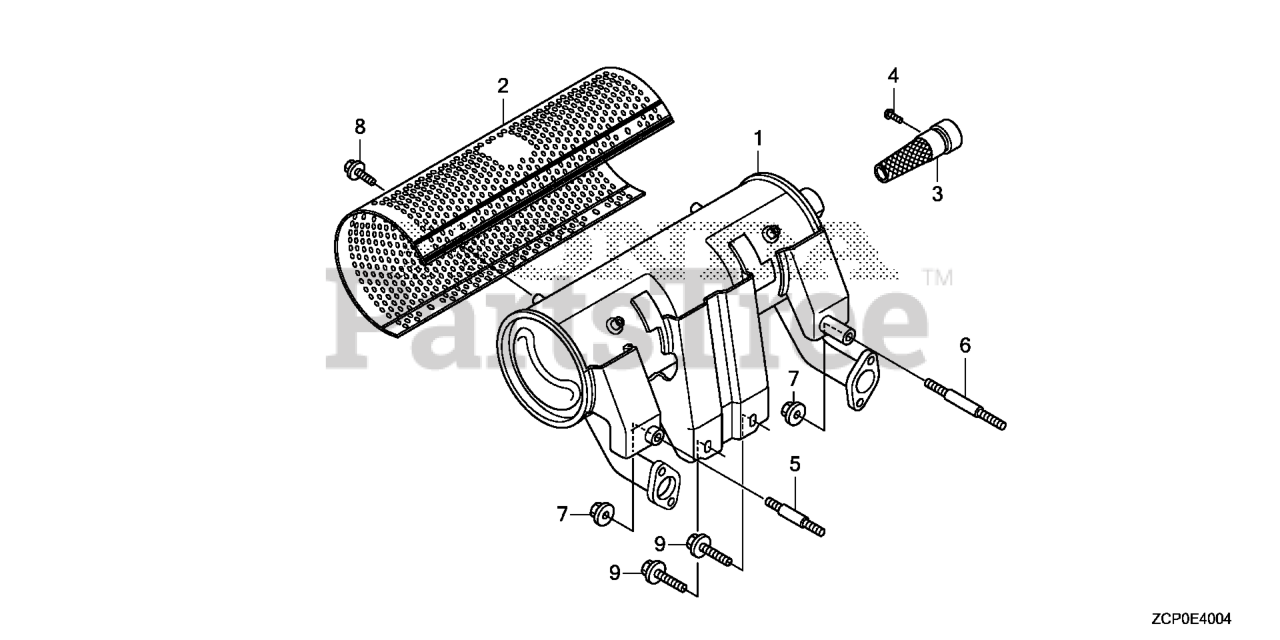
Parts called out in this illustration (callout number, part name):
1	MUFFLER (HIGH-L)
2	PROTECTOR, MUFFLER (HIGH) (FUTABA)
3	ARRESTER, SPARK
4	SCREW, TAPPING (5X8) (FOR SILVER MUFFLER)
5	BOLT, STUD (8X45)
6	BOLT, STUD (8X60)
7	NUT, FLANGE (8MM)
8	BOLT, FLANGE (6X8)
9	BOLT, FLANGE (8X20) Use up to Engine SN 1609606.
